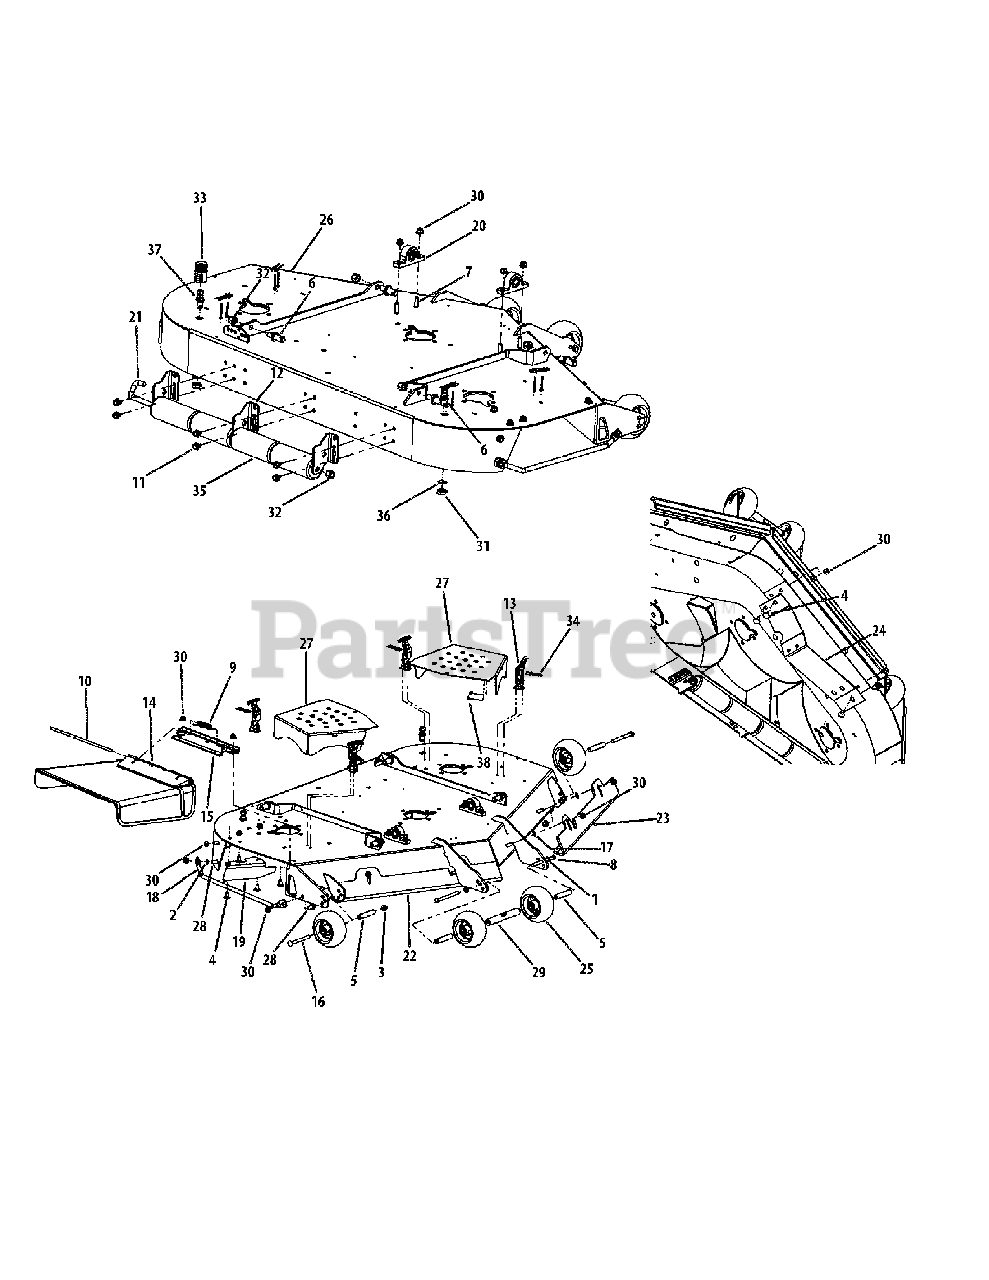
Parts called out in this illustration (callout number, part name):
1	Lock Washer, 3/8
2	Flat Washer, 3/8
3	Hex Nut, 3/8-16 Flange Lock
4	Carriage Bolt, 3/8-16 x .75 Lg.
5	Wheel Spacer
6	Pin, 5/8 Dia. x 1.2 Lg.
7	Carriage Screw, 3/8-16 x 1.25
8	Hex Cap Screw, 3/8-16 x 4.50
9	Spring Torsion, 0.639 ID x 2.16 LG
10	Defllector Chute Rod
11	Hex Index Washer Screw, 3/8-16, .5
13	T-Handle Draw Latch
14	Deflector Chute
15	Deflector Chute Bracket
16	Carriage Bolt, 3/8-16 x 4.00
17	Push Retainer
18	Finger Guard
20	Pillow Block
21	J-Hook w/ Threaded Roller
22	Right Hand Front Adjustment Skirt
23	Left Hand Front Adjustment Skirt
24	Baffle, 54" Adjustment
25	Complete Wheel, 5.00 Dia.
26	54" Deck Assembly
27	Deck Belt Cover
28	Carriage Bolt, 3/8-16 x 1
29	Ball Wheel Mounting Shaft
30	Lock Nut, Nylon Insert, 3/8-16
31	Hex Nut, M16-1.5
32	Lock Nut, Nylon Insert, 1/2-13
33	Water Nozzle Adaptor
34	Phillips Head Screw, 10-32
35	Front Roller
36	Lock Washer, 17 x 23.8 x 1.95
37	Deck Water Nozzle
38	Lock Nut, Nylon Insert, 10-32
